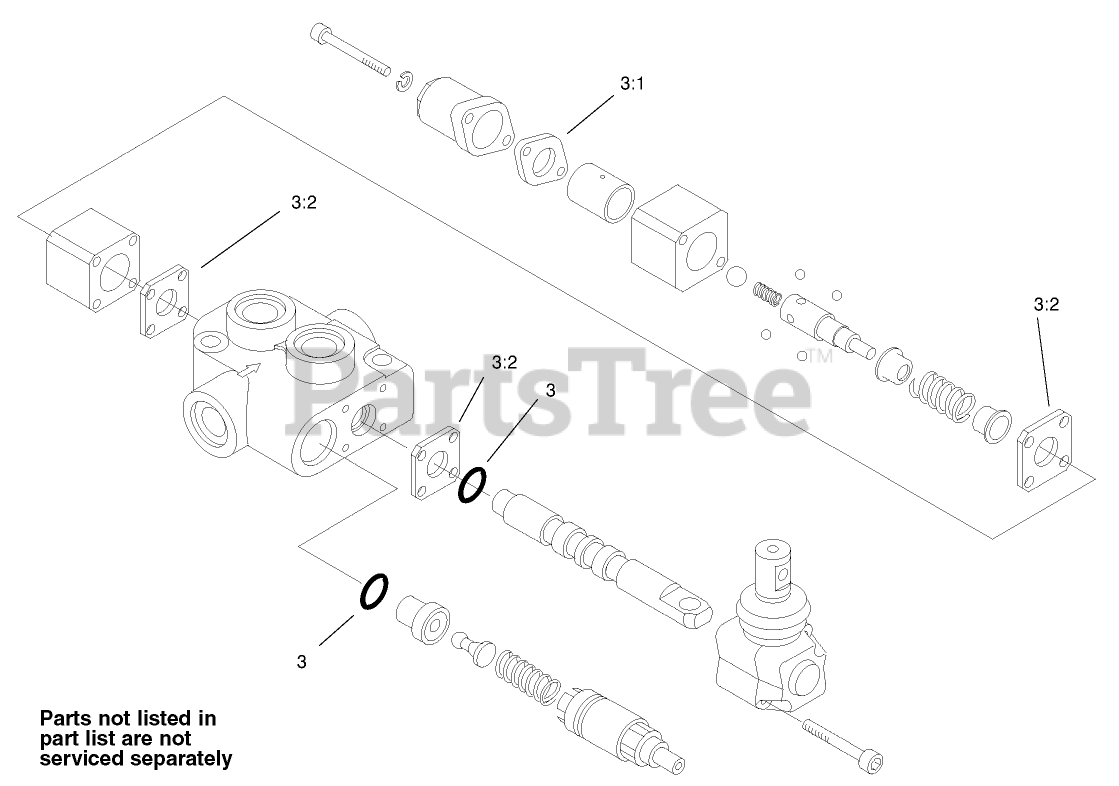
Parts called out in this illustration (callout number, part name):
3	SEAL KIT
3:1	GASKET
3:2	GASKET
